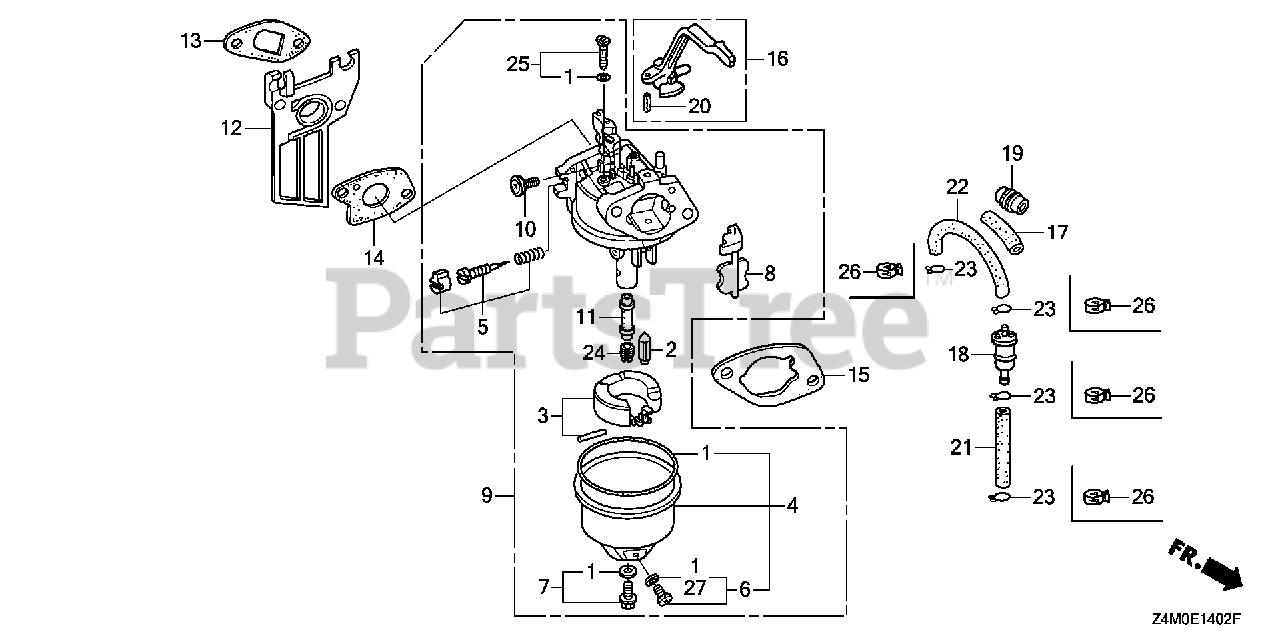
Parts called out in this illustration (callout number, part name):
1	GASKET SET (CARBURETOR NO.)
2	VALVE SET, FLOAT (CARBURETOR NO.) (SEAT NOT INCLUDED)
3	FLOAT SET
4	CHAMBER SET, FLOAT
5	SCREW SET (CARBURETOR NO.)
6	SCREW SET, DRAIN
7	SCREW SET (CARBURETOR NO.)
8	CHOKE SET
9	CARBURETOR ASSY. (BE62N B)
10	SCREW, THROTTLE STOP
11	NOZZLE, MAIN
12	INSULATOR, CARBURETOR
13	GASKET, INSULATOR
14	GASKET, CARBURETOR
15	GASKET, AIR CLEANER
16	LEVER, CHOKE
19	RUBBER, FUEL (9X15X20)
20	PIN, SPRING (2X12)
22	TUBE, FUEL (4.5X150) (FKM)
24	JET, MAIN (#72) (CARBURETOR NO.)
24	JET, MAIN (#75) (CARBURETOR NO.)
24	JET, MAIN (#70)
25	JET SET, PILOT (#35)
26	CLIP, TUBE (D8)
27	WASHER, PLAIN (6.2X10.7 DRAIN) (CARBURETOR NO.)
